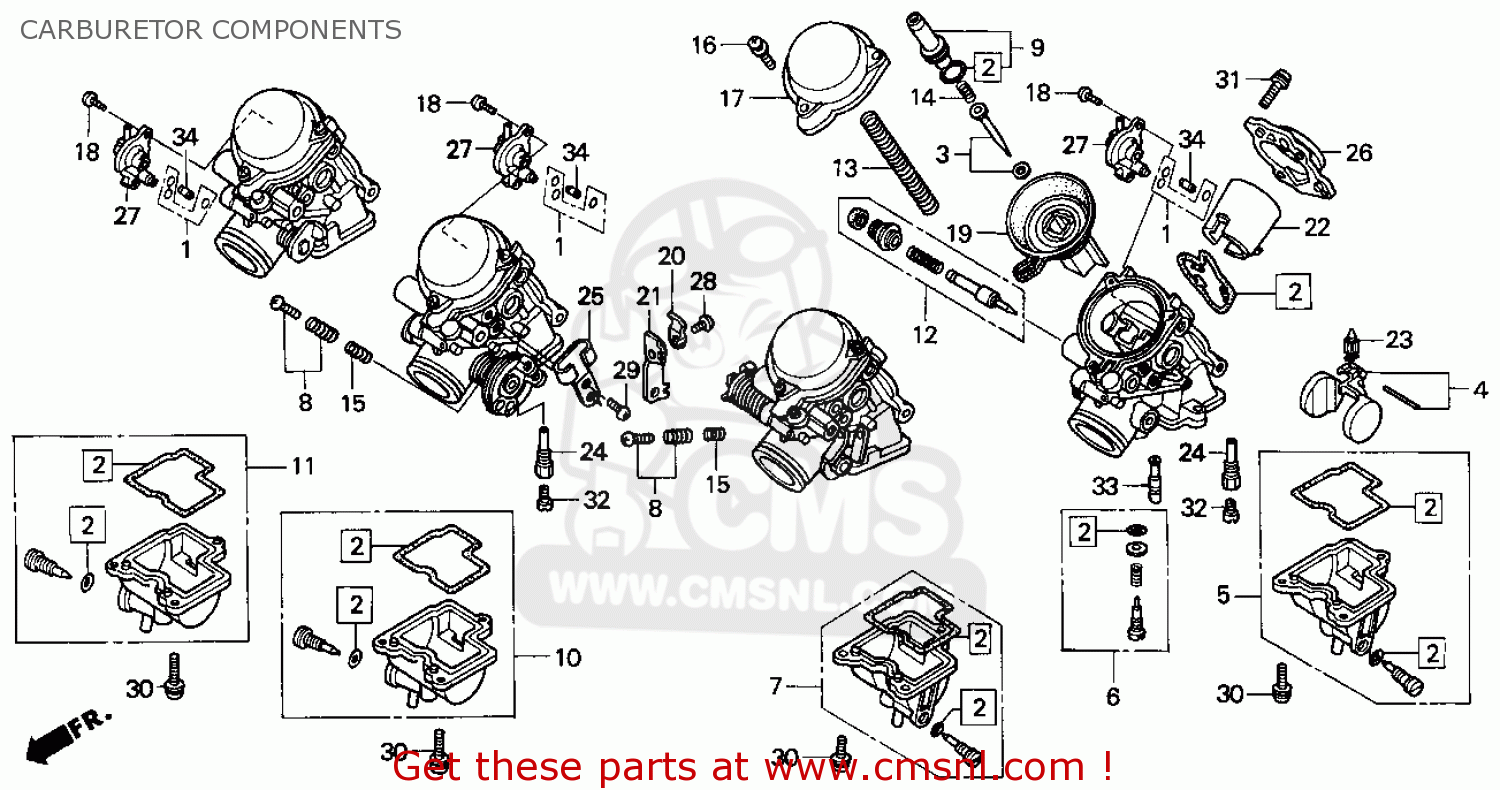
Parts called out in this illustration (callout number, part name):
1	GASKET SET D
2	GASKET SET,A
3	NEEDLE SET, JET
4	FLOAT SET
5	CHAMBER SET,FLOAT
6	SCREW SET
7	CHAMBER SET,FLOAT
8	SCREW SET
9	VALVE PLATE SET
10	CHAMBER SET,FLOAT
11	CHAMBER SET,FLOAT
12	STARTER VALVE SET
13	SPRING,COMPRESION
14	SPG,COMPRESSION,C
15	SPG,COMPRESSION,C
16	SCREW,PAN
17	TOP
18	SCREW
19	PISTON COMP VACUU
20	PLATE,STAY
21	PLATE,STAY
22	FUNNEL,AIR
23	VALVE COMP.,FLOAT
24	NEEDLE JET HOLDER
25	WIRE STAY
26	PLATE,FUNNEL SET
27	ACV,ASSY
28	SCREW-WASH.,4X10
29	SCREW-WASHER,5X10
30	SCREW-WASH. 5X16
31	SCREW-WASHER,4X14
32	JET,#122
33	JET,SLOW,#40
34	JET,SLOW AIR,#115
